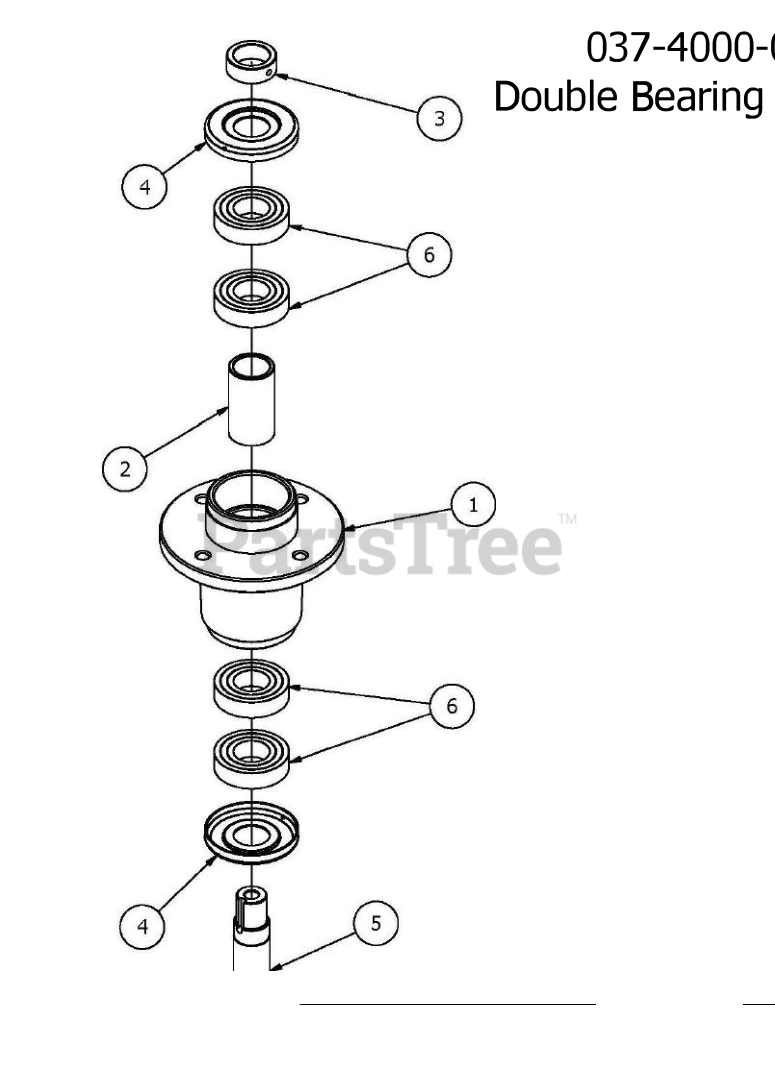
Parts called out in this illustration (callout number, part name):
1	4000 Series Spindle Housing
2	4000 Series Spindle Spacer
3	Locking Collar w/ 1/4" - 20 Set Screw
4	Spindle Dust Cap
5	Spindle Shaft
6	Bearing-6206
